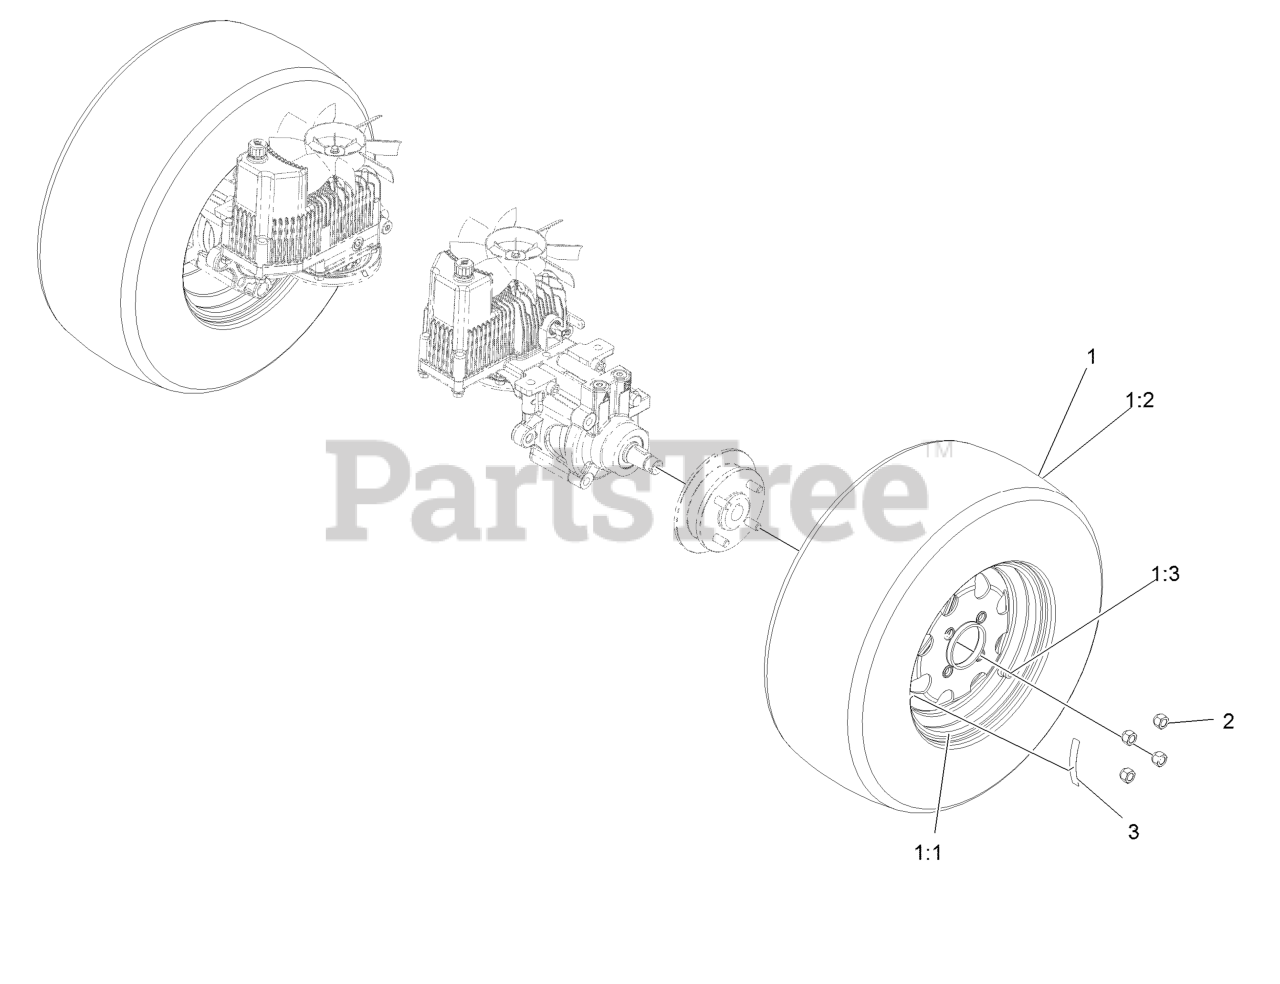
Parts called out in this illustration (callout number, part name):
1	Wheel And Tire ASM
1:1	Rim ASM
1:2	Tire
1:3	Stem-Valve
2	Nut-Lug 1/2-20
3	Decal-Torque, Wheel Hub Lug
